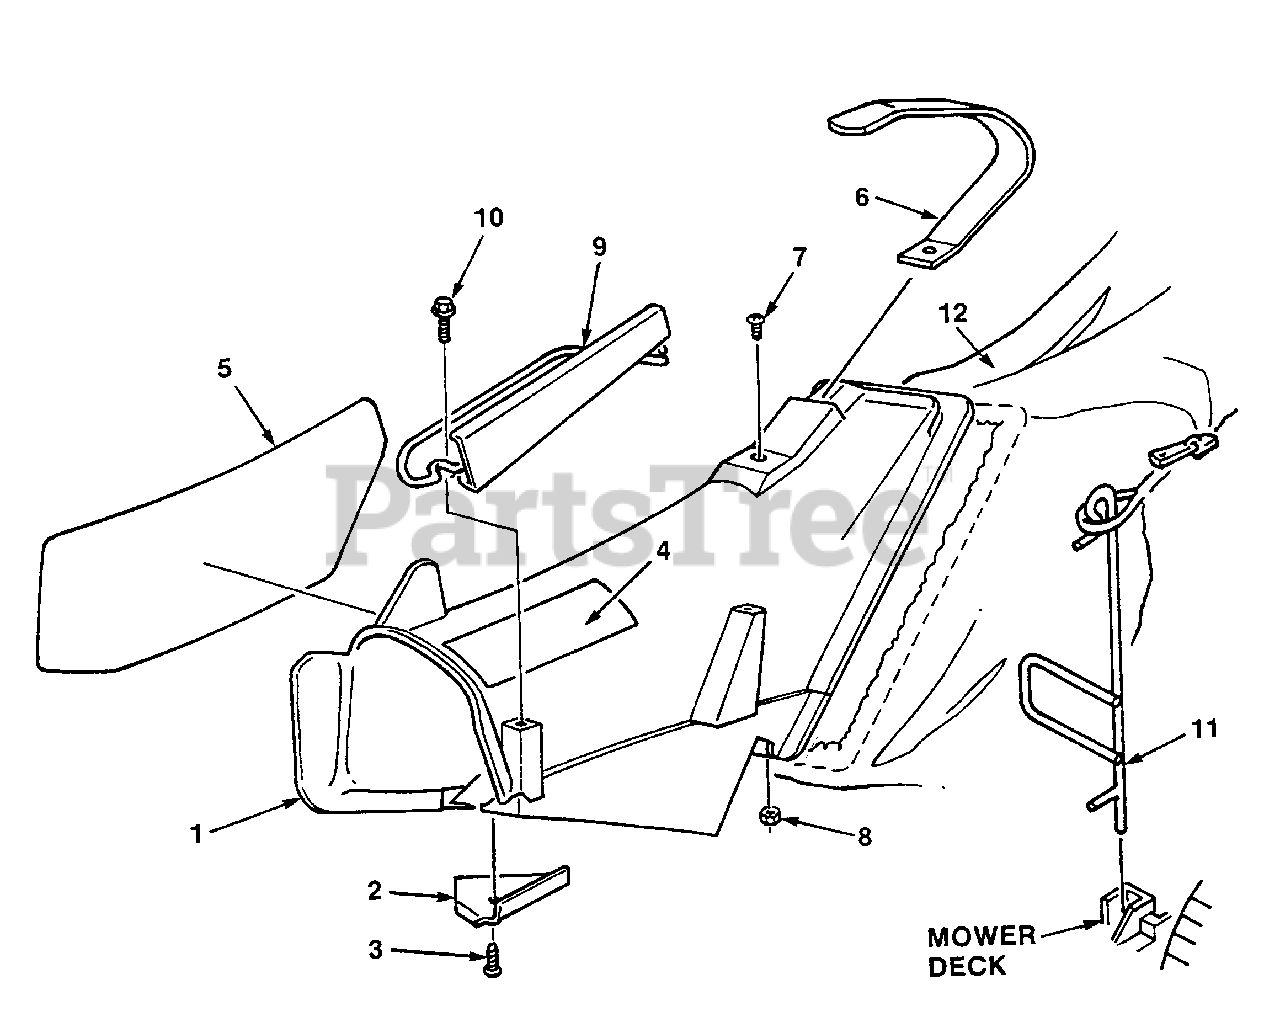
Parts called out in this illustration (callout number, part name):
1	ADAPTER & SCOOP
2	PLATE- Cover
3	SCREW- Rd hd
4	DECAL- Instruction
5	DECAL- Instruction
6	HANDLE- Adapter
7	SCREW- Truss hd.
9	RAIL AND GUIDE
10	SCREW- Hex hd
11	BAG- Support
12	GRASS BAG
